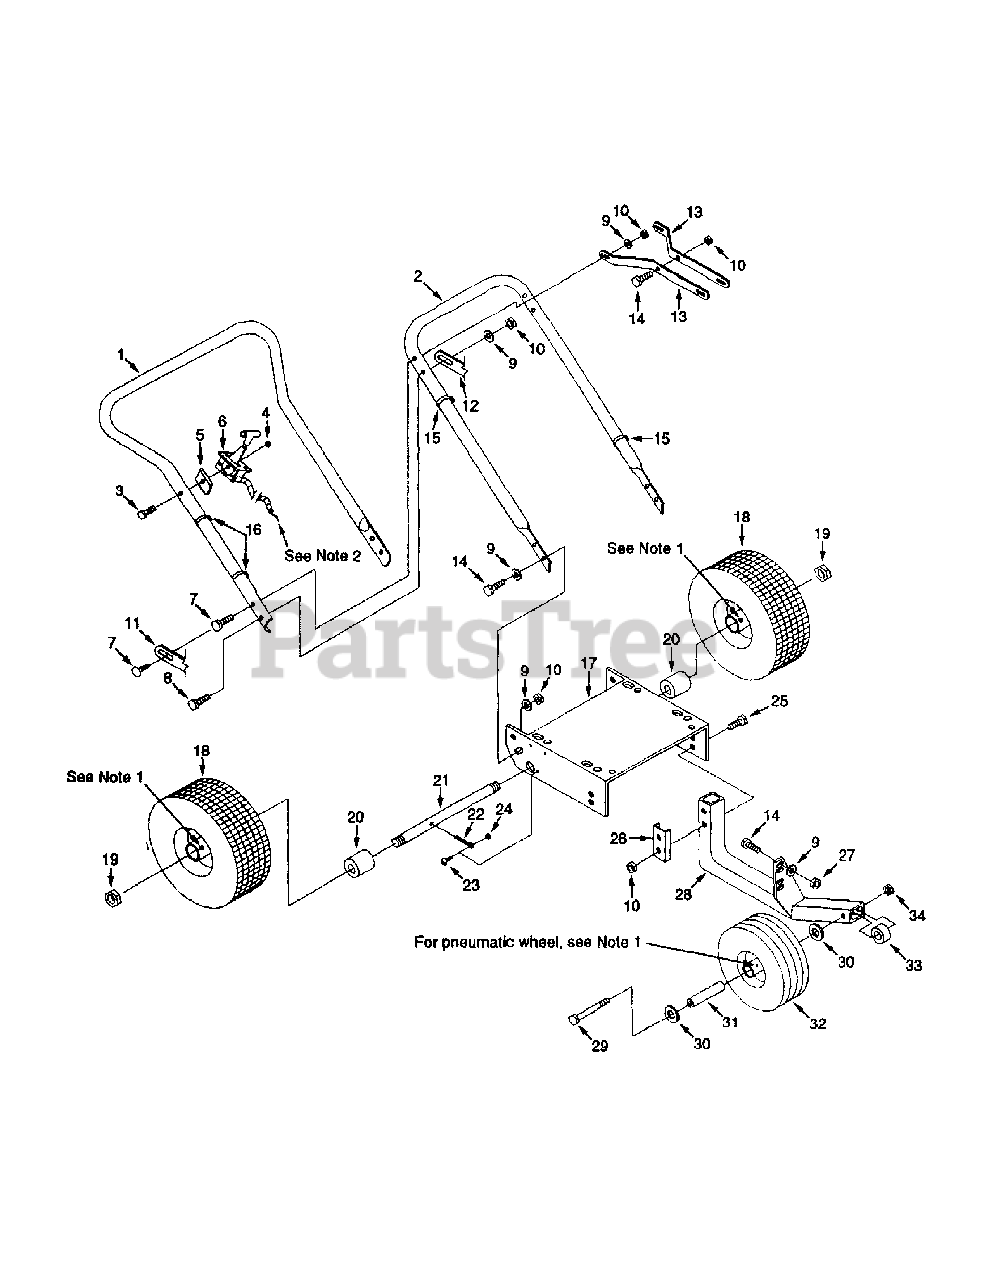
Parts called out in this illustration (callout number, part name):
1	Upper Handle
2	Lower Handle
3	Cap Screw, 1/4-20 x 1-1/2 Hex Head
4	Hex Nut, 1/4-20 Side Lock
5	Spacer, Throttle Mounting
6	Control Cable
7	Cap Screw, 5/16-18 x 1/3/4 Hex Head
8	Cap Screw, 5/16-18 x 1-1/2 Hex Head
9	Flat Washer, 5/16 SAE
10	Hex Nut, 5/16-18 Side Lock
11	Center Brace
12	Center Brace
13	Center Brace, Offset
14	Cap Screw, 5/16-18 x 3/4 Hex Head
15	Clamp, Throttle Cable
16	Clamp, Throttle Cable
17	Engine Base Plate
18	Wheel Assembly, 11 x 4.00-4
19	Hex Nut, 5/8-18 Nylock, Thin
20	Axle Spacer
22	Cotter Pin, 3/16 x 1-1/4
23	Machine Screw, #10-32 x 3/4 Round Head
24	Hex Nut, 5/8-18 Nylock, Thin
25	Cap Screw, 5/16-18 x 1-1/2 Hex Head
26	Support Plate, Front Wheel Frame
27	Hex Nut, 5/16-18 Stover Lock
28	Frame, Solid Front Wheel
28	Frame, Pneumatic Front Wheel
29	Cap Screw, 5/16-18 x 4 Hex Head
29	Cap Screw, 3/8-16 x 5 Hex Head
30	Flat Washer, 5/16 USS
30	Flat Washer, 3/8 USS
31	Sleeve, Solid Front Wheel
31	Sleeve, Pneumatic Front Wheel
32	Solid Wheel, 5 x 2 wutg 1/2 Bore
32	Pneumatic Tire L Wheel Assembly W/Bearing
33	Spacer, Inside Tube
34	Hex Nut, 5/16-18 Side Lock
34	Hex Nut, 3/8-16 Nylock
